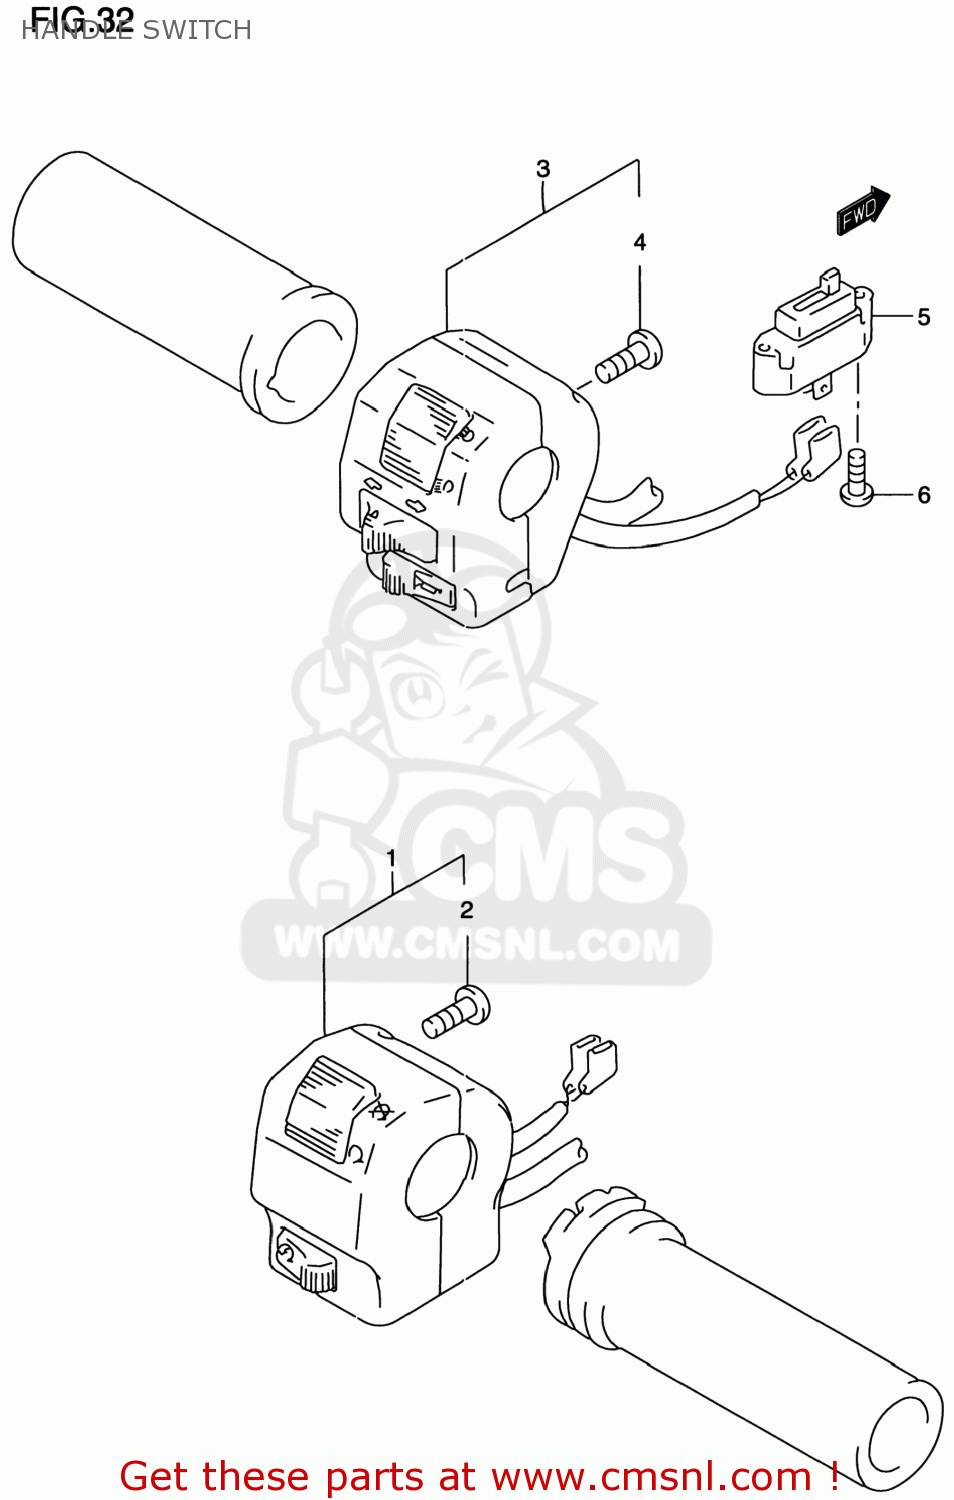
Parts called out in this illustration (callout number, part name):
1	SWITCH ASSY,HANDLE,R
2	SCREW
3	SWITCH ASSY,HANDLE,L
4	SCREW
5	SWITCH ASSY,CLUTCH
6	SCREW
